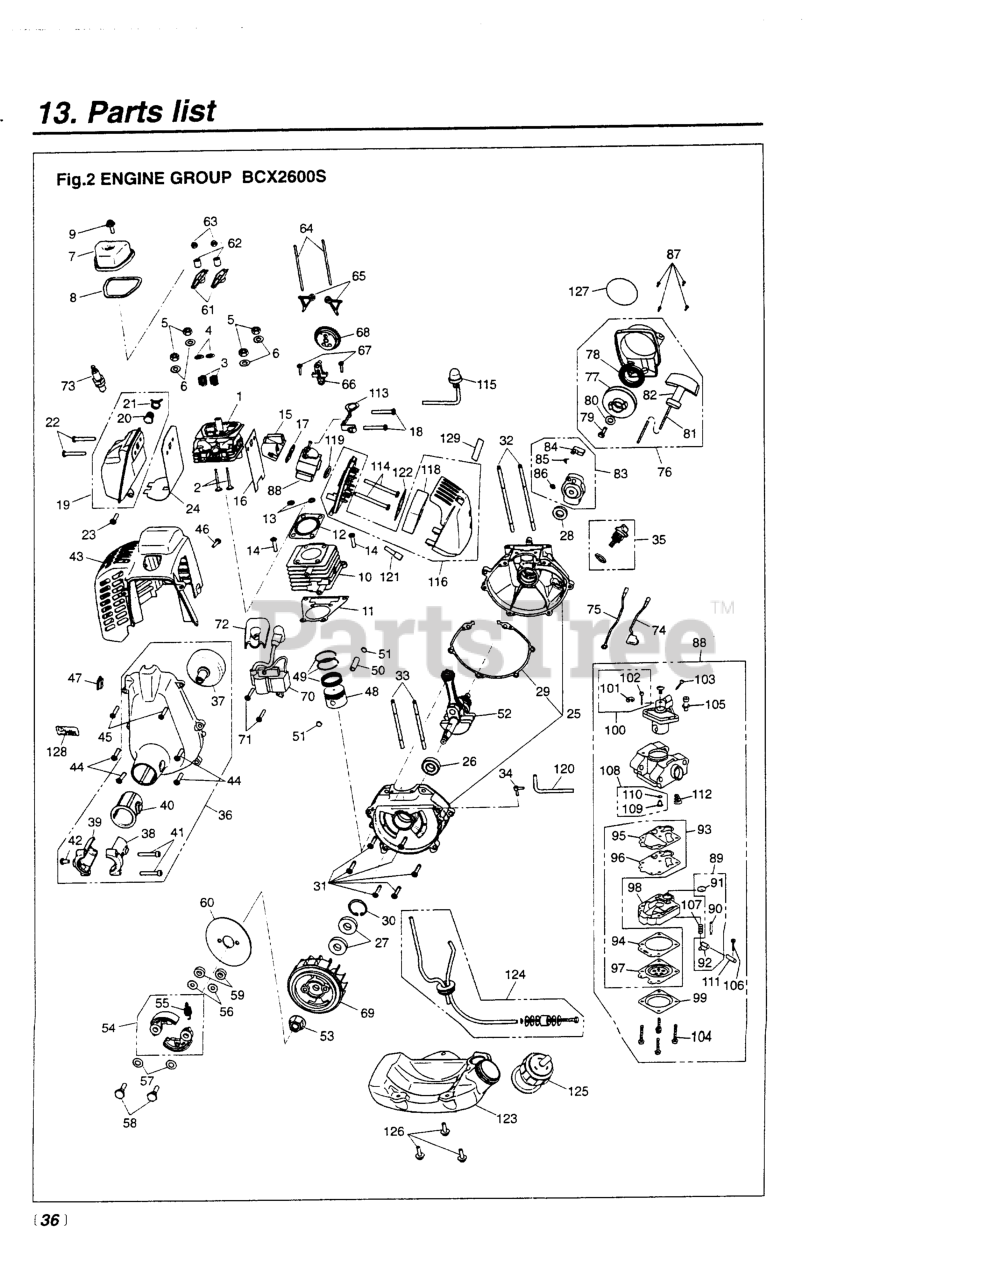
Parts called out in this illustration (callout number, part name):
1	182306 (REPLACES 2062-95110)
2	VALVE (RPLS 2062-11510)
3	SPRING, VALVE (RPLS 2062-11520
4	RETAINER (RPLS 2063-11530)
5	NUT (RPLS 2062-11310)
6	WASHER (RPLS 2062-11320)
7	COVER, VALVE (RPLS 2062-11410)
8	GASKET (RPLS 2062-11420)
9	SCREW (RPLS 2062-11430)
10	CYLINDER (RPLS 2062-12110)
11	GASKET, BASE (RPLS 2062-12210)
12	GASKET, HEAD (RPLS 2062-12220)
13	O-RING (RPLS 2062-12230)
14	SCREW (RPLS 2062-12240)
15	INSULATOR (RPLS 2062-13160)
16	GASKET (RPLS 2062-13120)
17	GASKET, CARB (RPLS 2062-13130)
18	SCREW (RPLS 2062-15220)
19	MUFFLER ASSY (RPLS 2062-15100)
20	ARRESTER (RPLS 2062-15140)
22	SCREW (RPLS 2062-15220)
23	SCREW (RPLS 2062-15230)
24	GASKET (RPLS 2062-15210)
25	CRANKCASE (RPLS 2062-95120)
26	BEARING (RPLS 2062-21420)
27	SEAL (RPLS 2062-21220)
28	SEAL (RPLS 2062-21210)
29	GASKET, BASE (RPLS 2062-21140)
30	RING, SNAP (RPLS 2062-21520)
31	SCREW (RPLS 5850-13210)
32	STUD (RPLS 2062-21160)
33	STUD (RPLS 2062-21170)
34	ELBOW (RPLS 2062-21620)
35	PLUG & 0-RING(RPLS 2062-95130)
36	HOUSING-A (RPLS 2063-31100)
37	DRUM, CLUTCH (USE 182298)
38	BRACKET (A) (RPLS -31210)
39	BRACKET (B) (REPLACES -31220)
40	CUSHION
42	BOLT (USE 3310-31720)
43	COVER, ENGINE (RPLS 2063-32110
44	SCREW (RPLS 2062-12240)
45	SCREW (RPLS 5850-32170)
46	SCREW (RPLS 2062-32140)
47	GROMMET (RPLS 1852-72121)
48	PISTON (RPLS 2063-41110)
49	RING (RPLS 2063-95140)
50	PIN, PISTON (RPLS 2062-41310)
51	BUTTON (RPLS 2062-41320)
52	SHAFT & GEAR (RPLS 2063-45000)
53	NUT (REPLACES 1650-43230)
54	SHOE, CLUTCH (RPLS.2063-51100)
55	SPRING
56	WASHER (REPLACES 1140-51230)
57	WASHER, SPRING (RPL 1970-51241
58	SCREW (REPLACES 2063-51250)
59	SPACER (RPLS 2063-51260)
60	DISK (RPLS 2063-51310)
61	ARM, ROCKER (RPLS 2062-61160)
62	PIVOT (RPLS 2062-61170)
64	ROD, PUSH (RPLS 2062-61210)
65	FOLLOWER, CAM (RPLS 2062-61310
66	BRACKET, CAM (RPLS 2062-61400)
67	SCREW (RPLS 2062-61610)
68	GEAR,CAM (RPLS 2062-61500)
69	ROTOR (RPLS 2063-71110)
70	COIL (RPLS 2062-71200)
71	SCREW, COIL (RPLS 2062-71310)
72	CAP, COVER (RPLS 2063-72140)
74	CORD (A)
75	CORD (B)
76	RECOIL (RPLS 2062-95150)
77	REEL (RPLS 5850-75120)
78	SPRING (RPLS 5850-75130)
79	SCREW (RPLS 5850-75140)
80	WASHER (REPLACES 1400-86280)
81	ROPE (RPLS 5850-75150)
82	KNOB (RPLS 5850-75160)
83	PULLEY ASSY
84	RATCHET (RPLS 5850-75220)
85	SPRING (RPLS 5850-75230)
86	RING, SNAP (RPLS 0308-00040)
87	SCREW (RPLS 2062-75310)
88	CARBURETOR (RPLS 2062-81000)
90	VALVE, INLET
91	SCREEN
92	LEVER
93	KIT, GASKET (D11-WYL)
94	GASKET
95	GASKET, PUMP
96	DIAPHRAGM, PUMP
97	DIAPHRAGM
98	BODY ASSEMBLY, PUMP
99	COVER, DIAPHRAGM
100	SWIVEL - A
101	RING, SPRING RETAINING
102	SWIVEL
103	SCREW, IDLE ADJUST
104	SCREW, COVER
106	SCREW, METERING LEVER PIN
107	SPRING, METERING LEVER
108	KIT, MAIN JET
109	JET
110	O-RING
111	PIN, METERING LEVER
112	SPRING, DIAPHRAGM PUMP
113	BRACKET (RPLS 2062-83110)
114	SCREW (RPLS 2062-83120)
116	CLEANER (RPLS 2062-82000)
118	ELEMENT (RPLS 2062-82150)
119	RING (RPLS 5850-83110)
120	HOSE (RPLS 2062-82310)
121	BREATHER ASSY (RPLS 2062-82400
122	SCREEN (SUB 2062-82160)
123	TANK (RPLS 2063-85000/85110)
124	FUEL LINE ASSY.
125	CAP (RPLS 2062-85200)
126	SCREW (RPLS 2062-85510)
127	LABEL, RECOIL (RPL 2063-91120)
128	LABEL, HOUSING (RPL 2063-91160
129	LABEL, CLEANER (RPL 2062-91180
